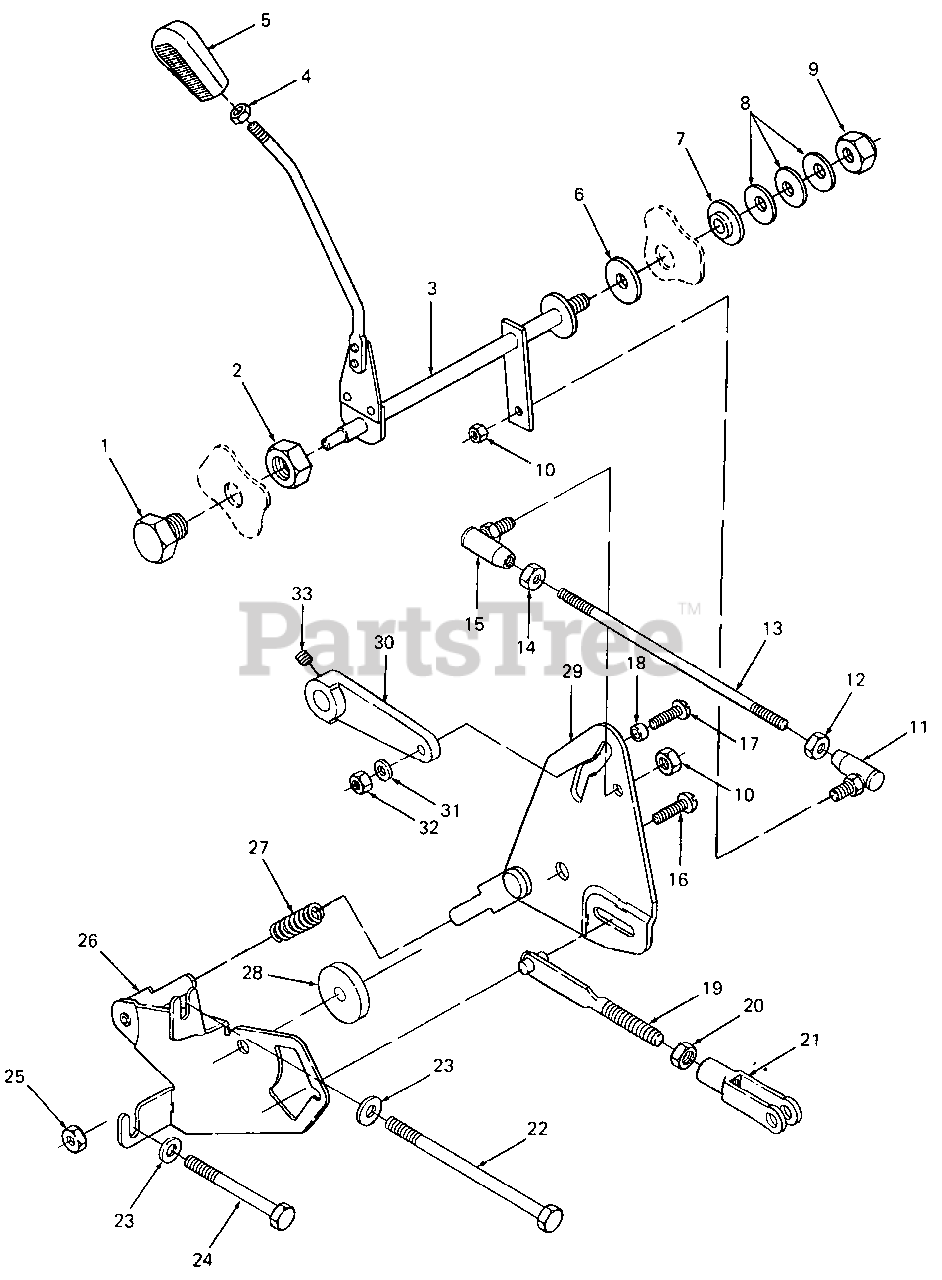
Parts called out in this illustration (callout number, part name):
1	Screw, Rockshaft Bearing, 3/4-16 X .75 Lg
2	Nut, Hex Jam, 3/4-16 GR5
3	Shaft Assy, Cross
4	Nut, Hex Jam, 3/8-16 GR5
5	Knob, Speed Control
6	Disc, Friction
7	Spacer, Shouldered
8	Washer, Bell
9	Nut, Hex Top Lock, 1/2-20
10	Nut, Hex Patch Lock, 5/16-24
11	Ball Joint, 5/16-24
12	Nut, Hex Jam, 5/16-24 Trd
13	Rod, Connecting
14	Nut, Hex Jam, 5/16-24 LH Trd
15	Ball Joint, 5/16-24 LH Trd
16	Screw, Truss Hd, 5/16-18 X 1
17	Screw, Truss Hd, 1/4-20 X 1
18	Spacer, 3/8 OD X .700
19	Rod, Control
20	Nut, Hex Jam, 3/8-24 GR5
21	Clevis Adjustment
22	Bolt, Hex Patch, 5/16-18 X 5.5 Lg GR5
23	Washer, Flat, .344 X .750 X .105 Thk
24	Bolt, Hex Patch, 5/16-18 X 3.0 Lg GR5
25	Nut, Hex Jam, 5/16
26	Arm Assy, Cam
27	Spring, Compression
28	Spacer, Shouldered
29	Cam Assy, Return
30	Pintle, Control
31	Washer, Lock, 1/4
32	Nut, Hex, 1/4
33	Set Screw, Socket w/Patch
